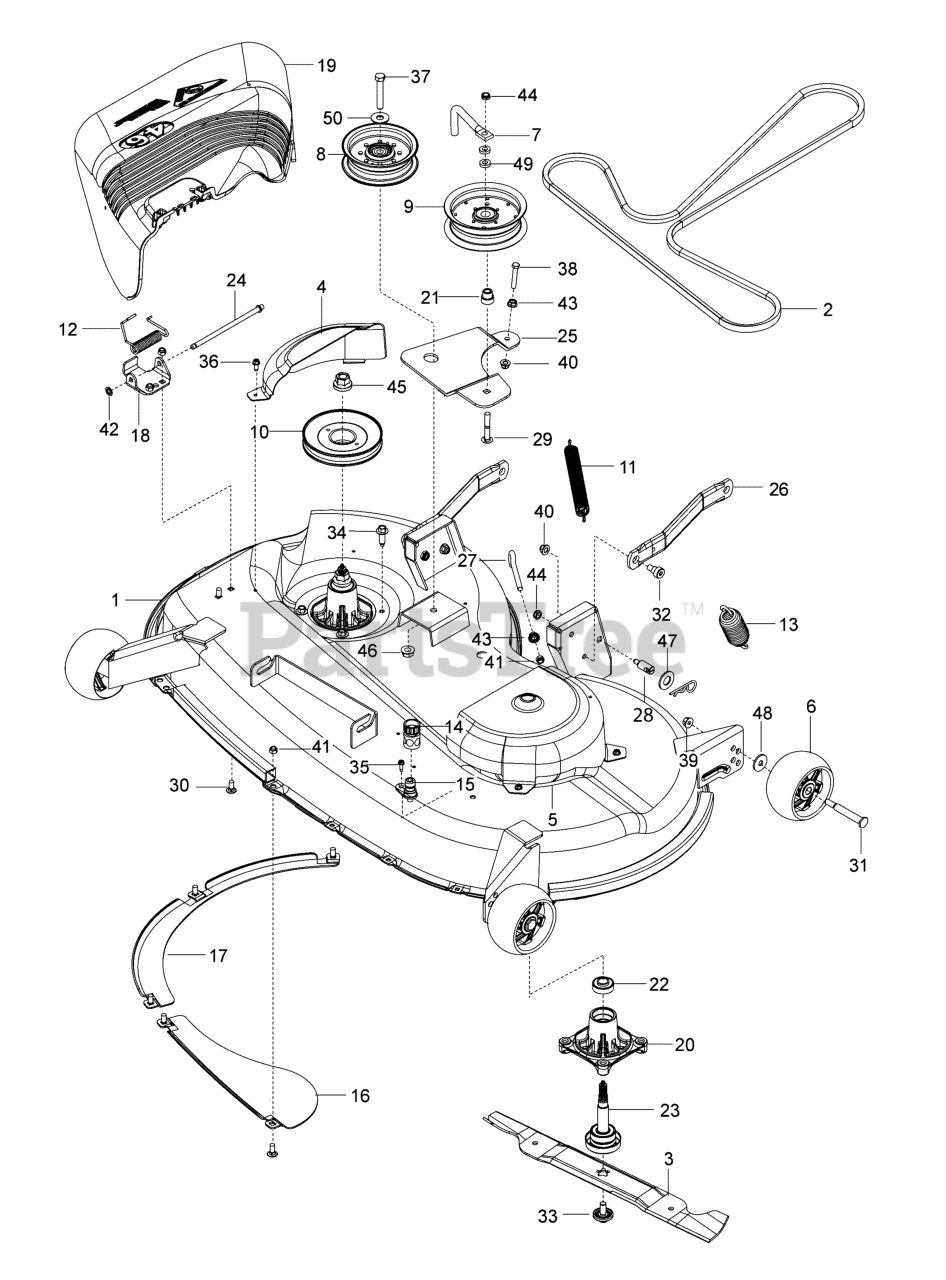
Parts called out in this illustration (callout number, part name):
1	DECK
3	Blade Mower Hi-Lift
4	GUARD, Pulley, Right
5	GUARD, Pulley, Left
6	WHEEL, Gauge
7	GUIDE, Belt
9	PULLEY, Idler
10	PULLEY, Blade
11	SPRING, Idler Pulley
12	Spring, Torsion
14	Coupling Quick Connect
15	Port Washout
16	Baffle Center Front
17	Baffle Front RH
18	Bracket, Deflector
19	Shield, Deflector
20	SPINDLE ASSEMBLY
21	BUSHING, Pulley
22	BEARING, Mandrel
23	SHAFT, Spindle
24	Rod, Hinge
25	ARM, Idler
26	HANGER, Deck
27	EYE BOLT
28	Stud Fastner W/'D'anti-Rotatio
29	BOLT, Round Head Square Neck, 3/8-16 x 2-1/4
30	BOLT, 5/16-18 X 3/4 GR. 5 ZD
31	Bolt, Shoulder
32	SCREW, 3/8-16 X 3/8 SKT HD
33	SCREW, 7/16-20 X 1 Hex Hd.
34	BOLT, .313-18 X 1.19
35	SCREW, 10-24 X 5/8
36	Capscrew, Hex Hd., 3/8-16 x 1 1/4
37	CAPSCREW, 7/16-14 X 2-1/2
38	Bolt Full Thd 5/16-18 x 1-1/4
39	NUT, 3/8-16, Lock
40	LOCKNUT, 5/16-18 HEX FLANGE NYLOC
41	Nut, Lock 5/16-18 unc
42	Nut, Push
43	NUT, 5/16-18 HEX WHIZ LOCK
44	LOCKNUT, 3/8-16 HEX JAM NYLOC
45	Nut, Toplock, Flanged
46	Nut Lock Flange 7/16-14 Gr. 5
47	WASHER, 1- 5/16 13 GAUGE
49	WASHER, 3/8
50	WASHER, 7/16
